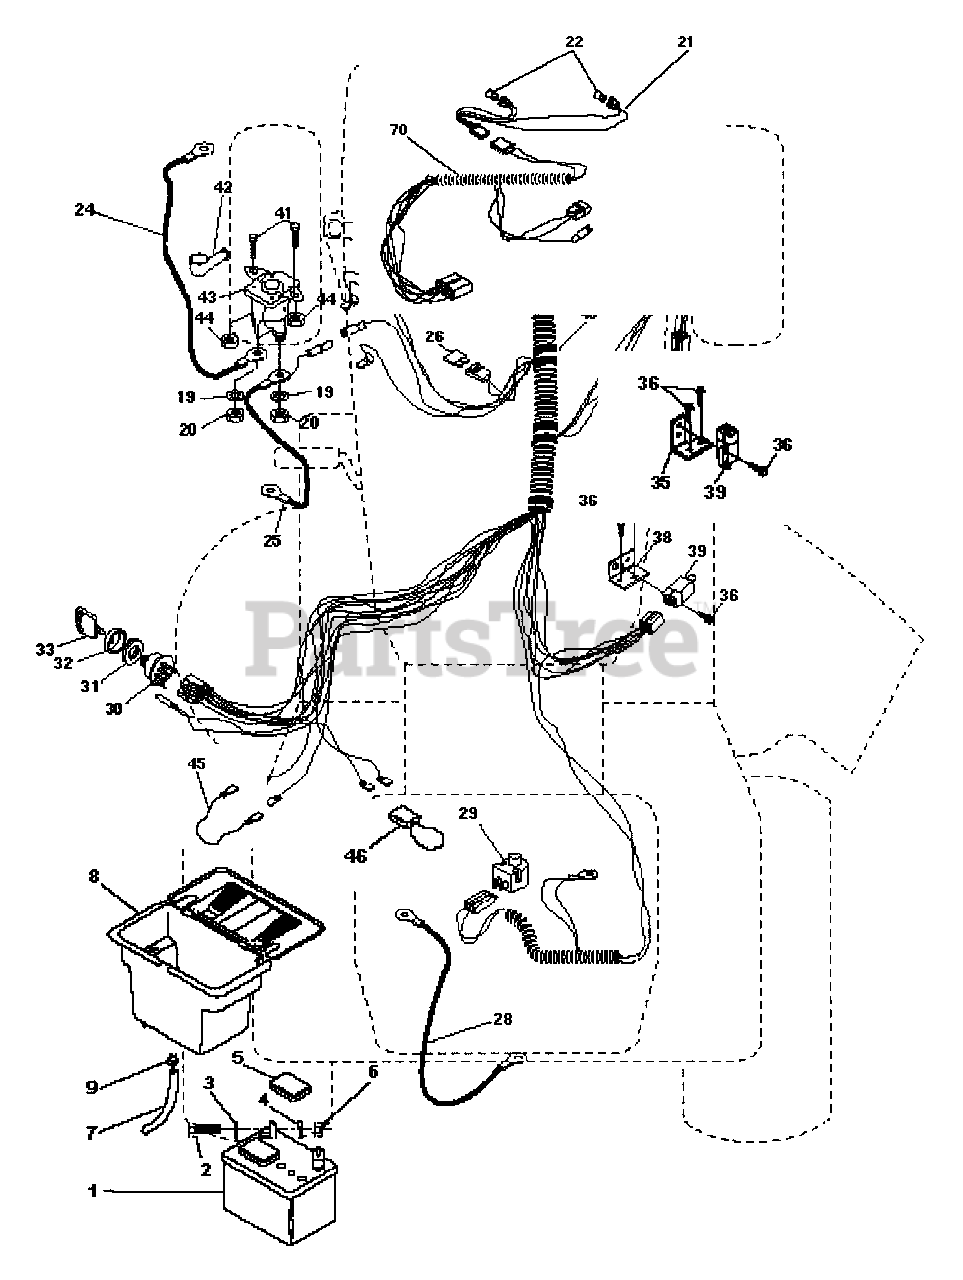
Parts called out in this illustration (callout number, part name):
1	Battery 12 Volt 25 AMP
2	Bolt Hex Hd 1/4-20unc X 3/4
3	Washer 9/32 X 5/8 X 16 Ga.
4	Washer Lock Hvy Helical 1/4
5	Caps Battery 20/25/30 AMP
6	Nut Fin Hex 1/4-20 Unc
7	Tube Plastic 12"
8	Case Battery
9	Clamp Hose Olive
19	Washer Lock 1/4
20	Nut Jam Hex 1/4-20 Unc
21	Harness Asm Light W/4152j
22	Bulb Light #1156
24	Cable Battery 6 Ga 11" red
25	Cable Battery 6 Ga 44" red
26	Fuse 30 AMP Auto Green
28	Cable Ground 6 Ga 12" black
29	Switch Plunger Nc Gray
30	Switch Ign 4 pos w/lights
31	Nut Ignition
32	Cover Sw Ignition
33	Key Ign Modleded Generic
35	Bracket Switch Clutch
36	Screw Tap Hex #10-24unc X 1/2
38	Bracket, Switch, Interlock
39	Switch Intlk Clutch Red 4 Term
40	Harness Ignition LT PL Mech
41	Bolt Blk Fin Hex 1/4 - 20 x 3/4
42	Cover Terminal Red
43	Solenoid
44	Nut Keps Hex 1/4-20 Unc
45	Adapter Ammeter
46	Protection Wire Loop
70	Harness, Eng.
